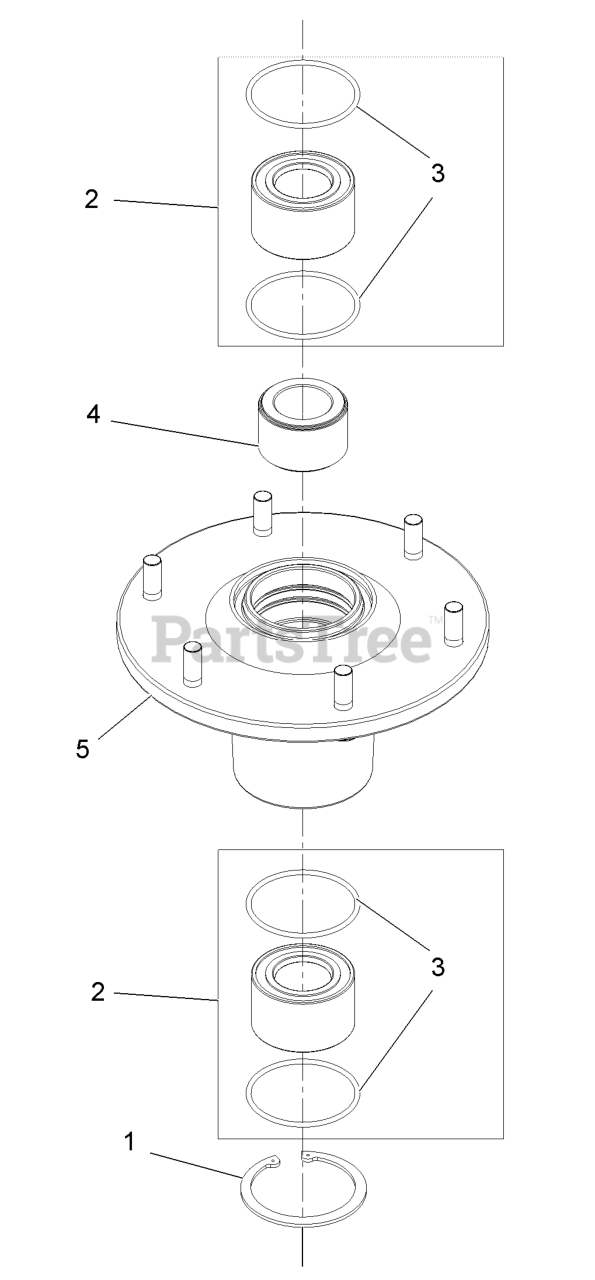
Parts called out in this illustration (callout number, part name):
1	Ring-Retaining
2	Asm, Bearing W/O-Rings
4	Spacer, Bearing
5	Asm, Housing W/Studs
